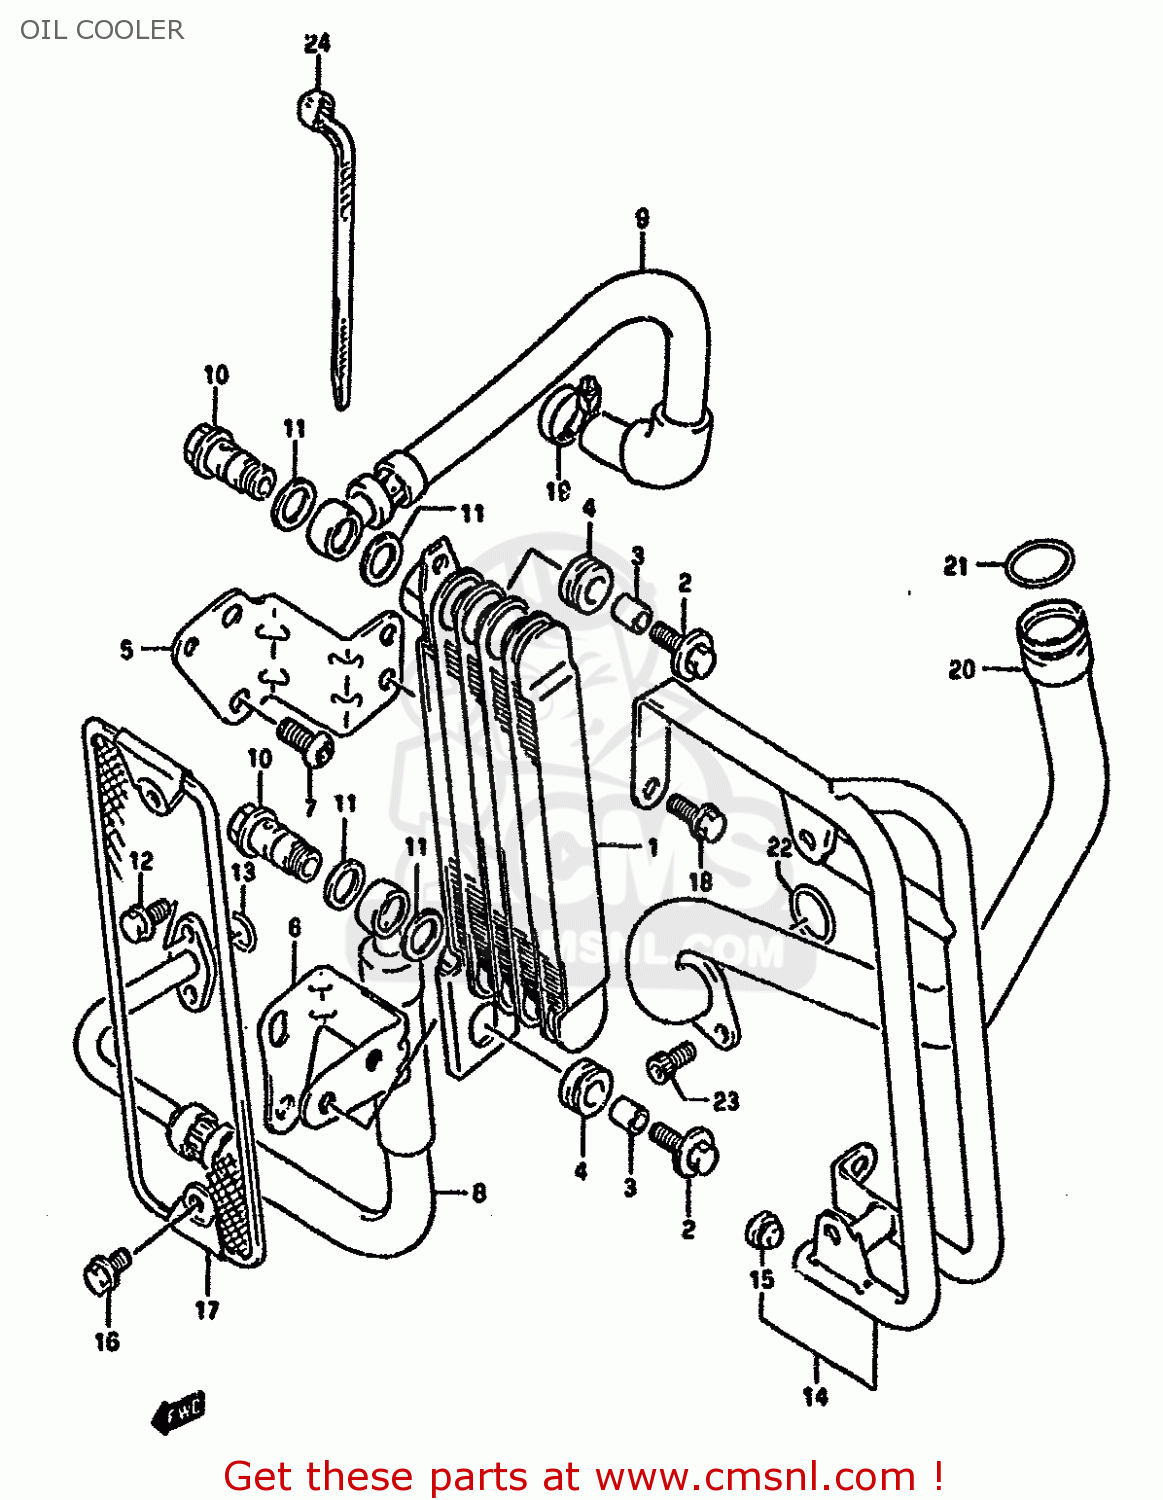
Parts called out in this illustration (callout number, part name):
1	COOLER ASSEMBLY,OIL
2	BOLT 6X20
3	SPACER (6.8X10X10)
4	CUSHION
5	BRACKET,OIL COOLER UPR
6	BRACKET,OIL COOLER,LOWER
7	BOLT(8X12)
8	HOSE,OIL COOLER NO.1
9	HOSE,OIL COOLER NO.2
10	BOLT UNION
11	GASKET(14X20X1.5) (NAS)
12	BOLT
13	O RING(D:2.4,ID:12.3)
14	GUARD,OIL COOLER
15	PLUG(OD:13)
16	BOLT
17	BUMPER,OIL COOLER
18	BOLT
19	CLAMP
20	PIPE COMP,OIL RETURN
21	O RING(D:3.7,ID:21.7)
22	O RING(D:2.4,ID:23.7)
23	BOLT
24	CLAMP(L:125)
